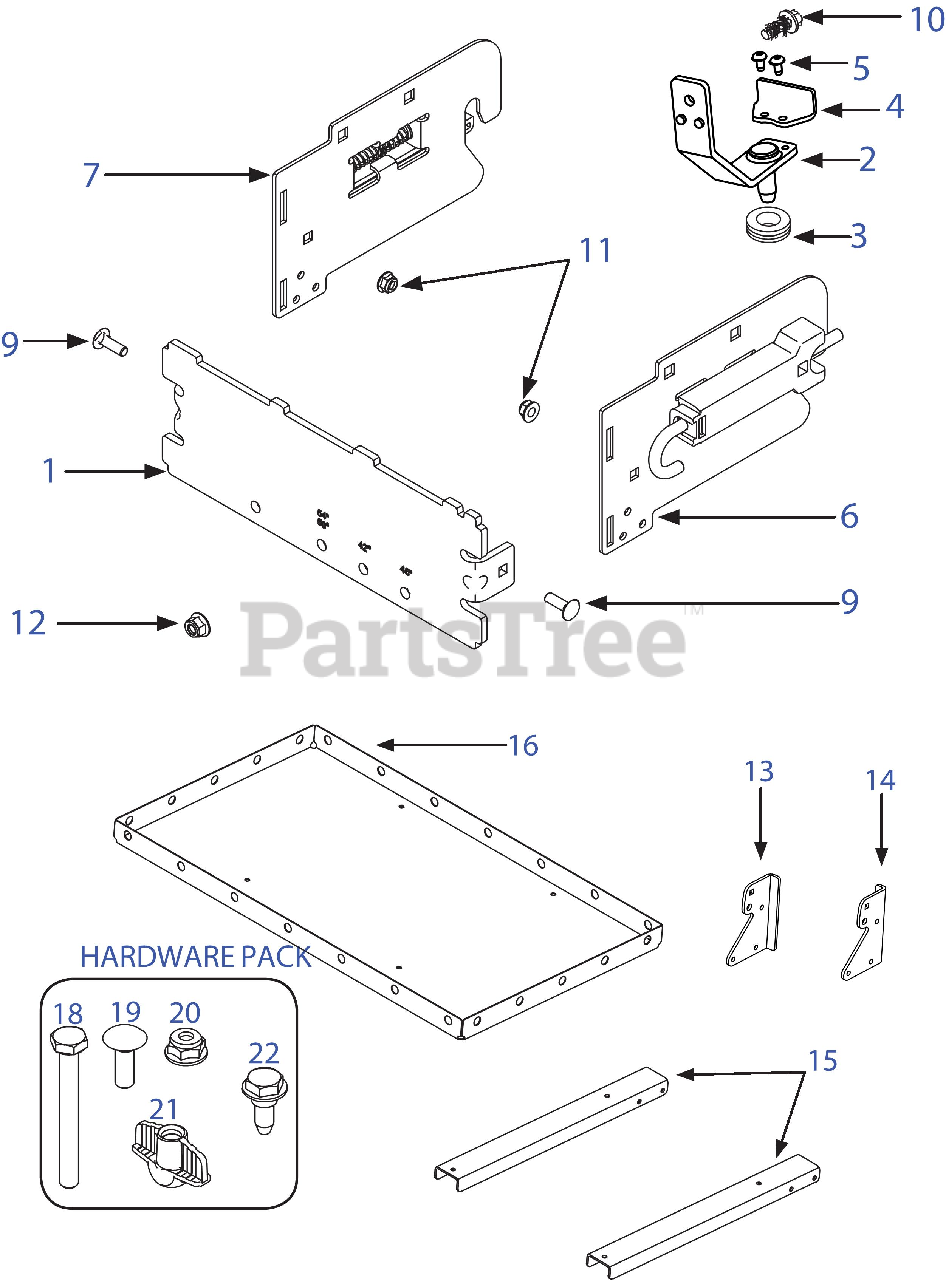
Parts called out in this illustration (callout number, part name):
2	Pin Hitch Support Assembly
3	Rubber Grommet
4	Hitch Support Bracket
5	Torx Screw: 1/4-20
6	RH Bracket Assembly
7	LH Bracket Assembly
9	Carriage Screw: 5/16-18: 1.0
10	Hex Screw:3/8-16: 1.0
11	Nylon Lock Nut:5/16-18
12	Flange Lock Nut:3/8-16
13	LH Cargo Hinge Bracket
14	RH Cargo Hinge Bracket
15	Cargo Support Bracket
16	Cargo Carrier
17	Cargo Carrier Hardware Pack
18	Hex Screw:1/4-20: 2.25
19	Carriage Screw:1/4-20: .75
20	Flange Lock Nut:1/4-20
21	Wing Nut:1/4-20
22	Shoulder Screw:.3175 x .188: 1/4-20
